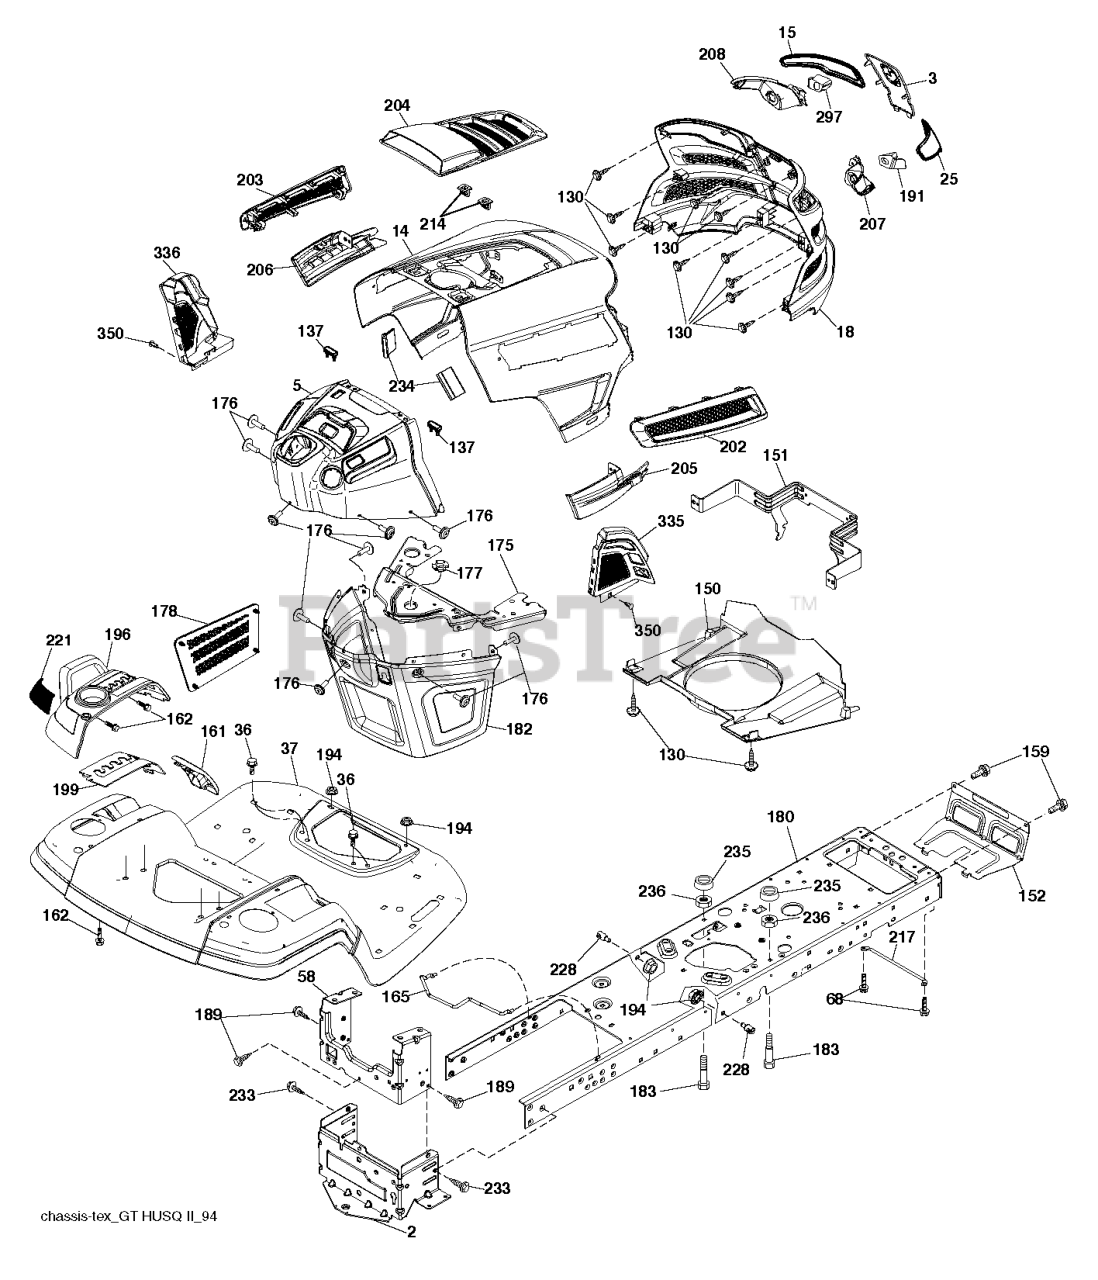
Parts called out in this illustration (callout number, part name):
2	DRAWBAR.LOWER.2PC.18/22
3	APPLIQUE.SUBASM.GT.HUSQ.II
5	DASH.UPP.GT2.DUAL.RD.PTO.MCHOK
14	HOOD.ASM.HUSQVARNA.GT.TEX.ORAN
15	LENS.HEADLIGHT.LH.GTII.2011
18	GRILLE.SUBSTRATE.2011.
25	LENS.HEADLIGHT.RH.GTII.2011
36	SCREW 5/16"
37	FENDER.PNT.TX.GT.CH/FW.ORANGE
58	DRAWBAR.UPPER.2PC,LRG.FENDER
68	Screw 5/16-18 x 1/2 Hex, Self Tapping 5/16-18 x 1/2
130	SCREW.#10 X 0.750.BOS
137	BUMPER DASH
150	AIR.DUCT.GTV2(2.54"RING HEIGHT
151	BRACKET.PIVOT.HOOD.GT.HUSQ.II
152	SHIELD.BROWNING/DEBRIS
159	SCREW, 3/8-16X3/4
161	CONSOLE.FUEL.WINDOW.HU
162	SCREW.HI-LO.CONSOLE
165	SUPPORT.TANK.REAR.B/TE
175	PLATE.CROSSMEMBER.HUSQ
176	SCREW.#10-24X5/8.RN.QU
177	BUSHING, STEERING
178	CARGO.ASM.NET.TXGT.W/C
180	CHASSIS.STAMPING.LT/GT
182	DASH.LOWER.COMMON.12V.ADAPTOR
183	BOLT.5/16-18X1-1/4 FULL THD
189	SCREW
191	INSERT.REFLECTIVE.RH.HUSQ.GTII
194	NUT LOCK HEX FLANGE 5/16-18
196	CONSOLE.ASM.DCKLFT.W/RF.HQ.DLR
199	PLATE.DECK.LIFT.HUSQVARNA.GT
202	VENT.SIDE.RH.GT.HUSQ.II.
203	VENT.SIDE.LH.GT.HUSQ.II.498
204	VENT.TOP.HUSQ.GT2
205	SIDE.TRIM.RH.GT.HUSQ.II
206	SIDE.TRIM.LH.GT.HUSQ.II.GRAY
207	BEZEL LIGHT.RH.GT.II.MYLAR
208	BEZEL LIGHT.LH.GT.II.MYLAR
214	CLIP.RETAINER.TINNER.
217	ROD.PIVOT.HOOD
221	REFLECTOR.LH.TEX GT HU
228	STUD.FASTNER.W/ANTI-ROTATE
233	BOLT.SHOULDER
234	BUMPER.HOOD.TEX.HUSQVARNA
235	SPACER FENDER
236	NUT.CENTERLOCK.5/16-
297	INSERT.REFLECTIVE.LH.HUSQ.GTII
335	COVER.LOWER.DASH.RH.BLACK
336	COVER.LH.CLOSE.OUT
350	CLIP.X-MAS.TREE
